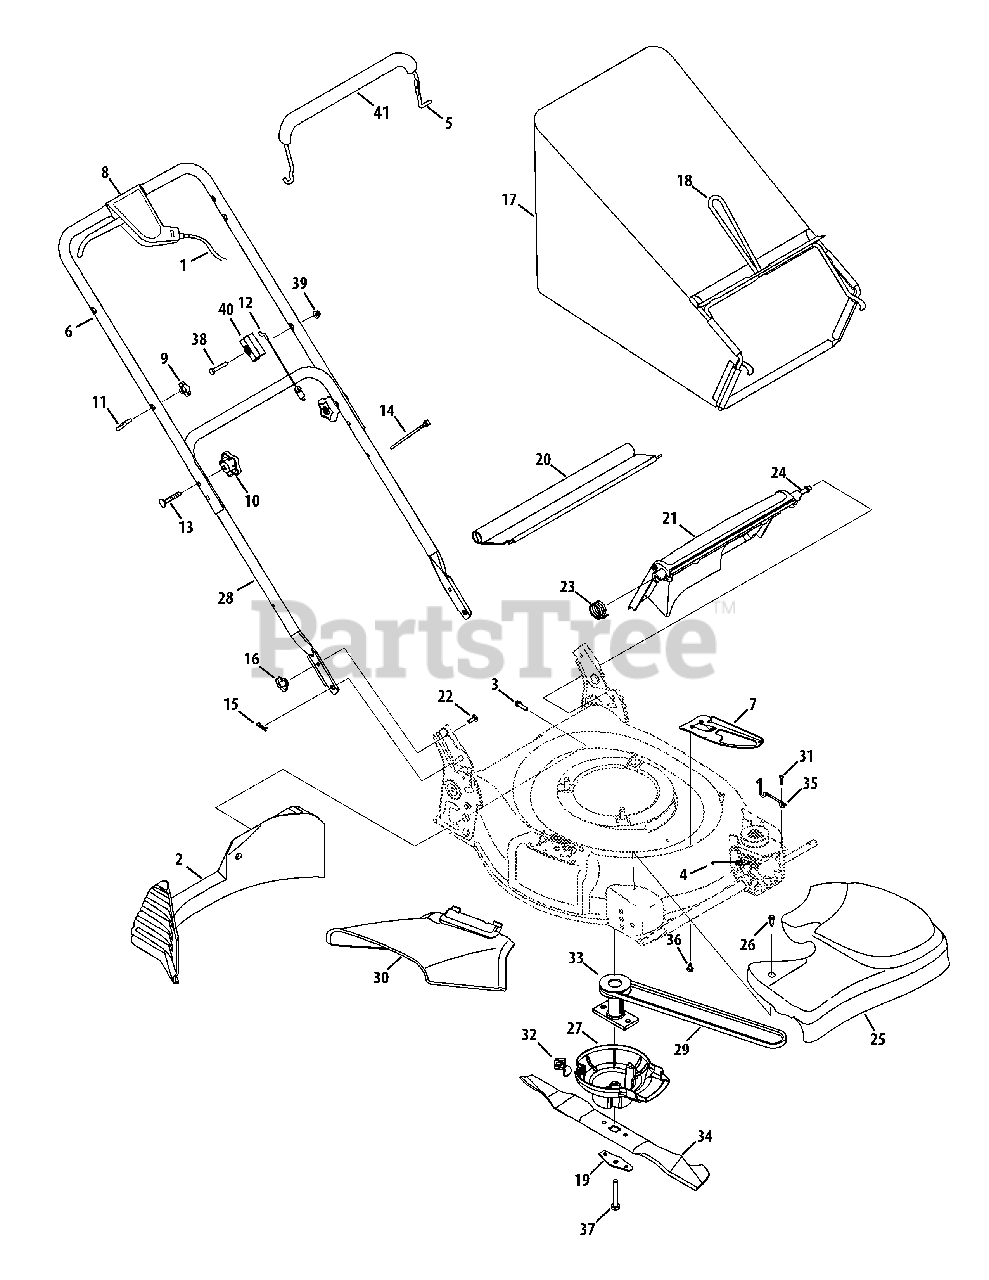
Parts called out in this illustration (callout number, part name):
1	Variable Speed Cable
2	Rear Baffle 21" Rd.
3	Screw, 1/4-15 x 1.000
4	Extension Spring
5	Blade Control
6	Upper Handle
7	Cable Mount Bracket
8	Control Lever Assembly
9	Handle Knob
10	Star Knob
11	Eye Bolt
12	Control Cable - 37.02
13	Carriage Bolt, 5/16-18 x 2.0
14	Cable Tie
15	Cotter Pin
16	Wing Nut
17	Grass Bag
18	Grass Bag Frame
19	Blade Bell Support
20	Rear Trailing Shield
21	Rear Discharge Door
22	Carriage Bolt, 1/4-20
23	Torsion Spring - RH
24	Pivot Rod
25	Transmission Cover
26	Shoulder Screw, # 12 -24
27	Engine Baffle
28	Lower Handle
30	Side Discharge Chute
31	Torx Screw
32	Baffle Bracket
33	Blade Adapter Assembly
34	21" Mulching Blade
35	Belt Keeper Wire
36	Scr., 1/4-14 x.625
37	Hex Screw, 3/8-24 x 2.50
38	Hhcs, 1/4-20 x 1.50
39	Nut, Flglk, 1/4-20
40	Mount, Cable
41	Bail Cover
